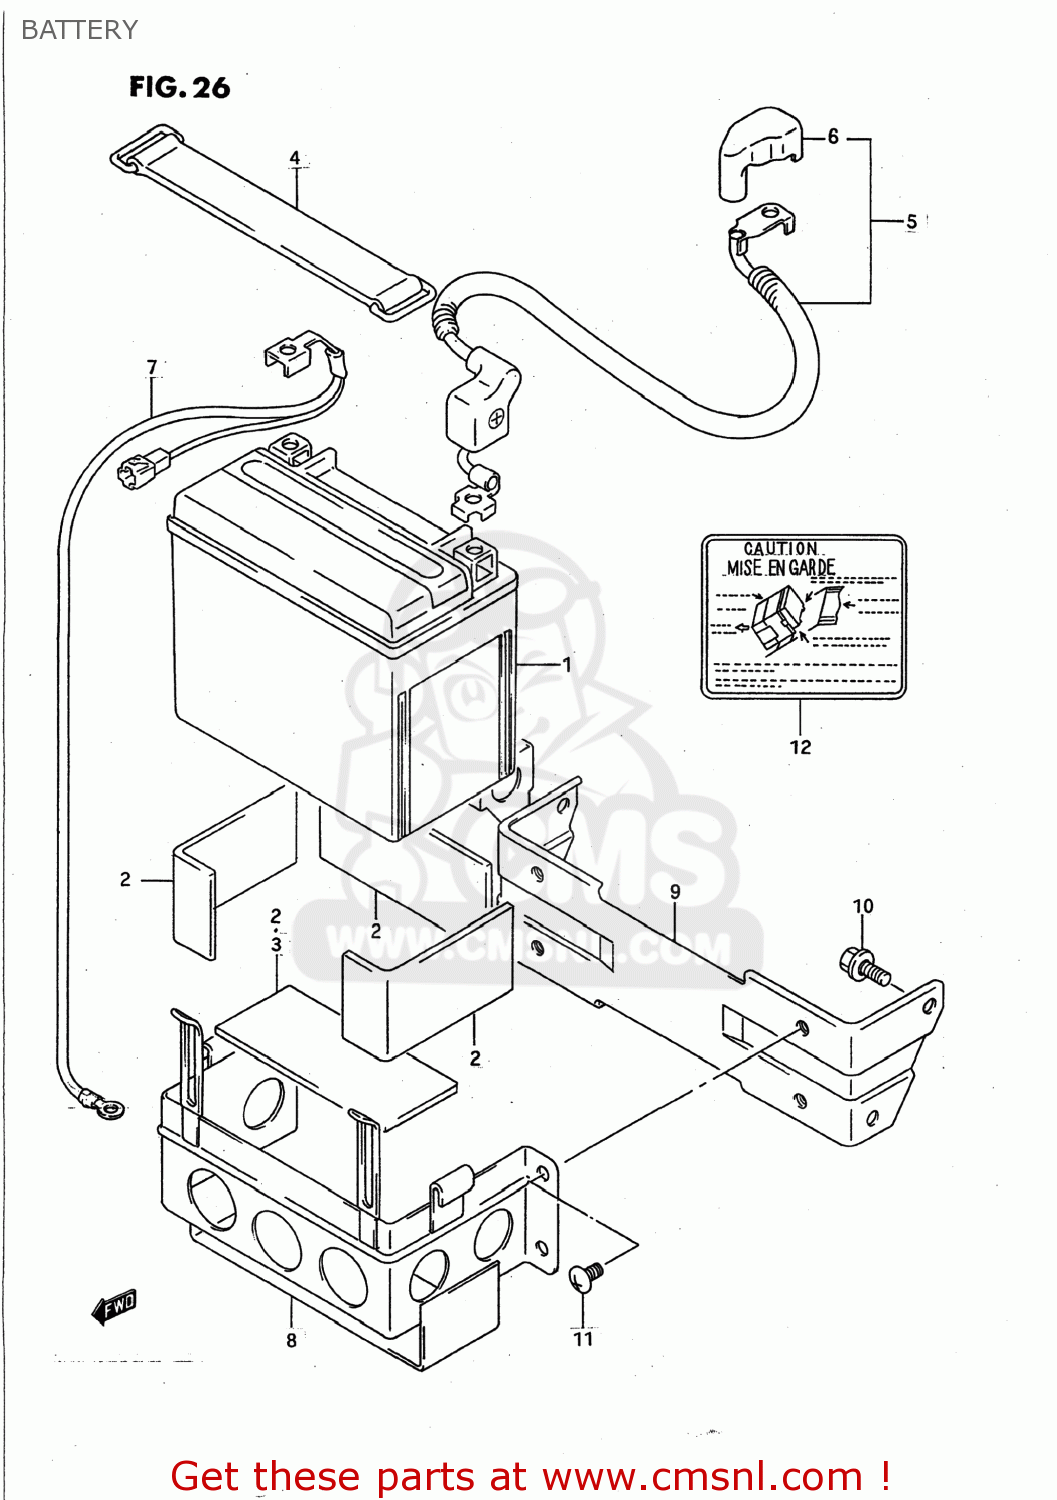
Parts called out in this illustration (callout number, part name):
1	BATTERY ASSEMBLY (12V) YTX
2	PROTECTOR(170X95X3.0)
3	PROTECTOR,BATTERY
4	BAND
5	WIRE,BATTERY PLUS
6	CAP,BATTERY PLUS
7	WIRE,BATTERY MINUS
8	HOLDER,BATTERY
9	BRACKET,BATTERY HOLDER
10	BOLT
11	SCREW 6X12
12	PLATE,BATTERY CAUTION
